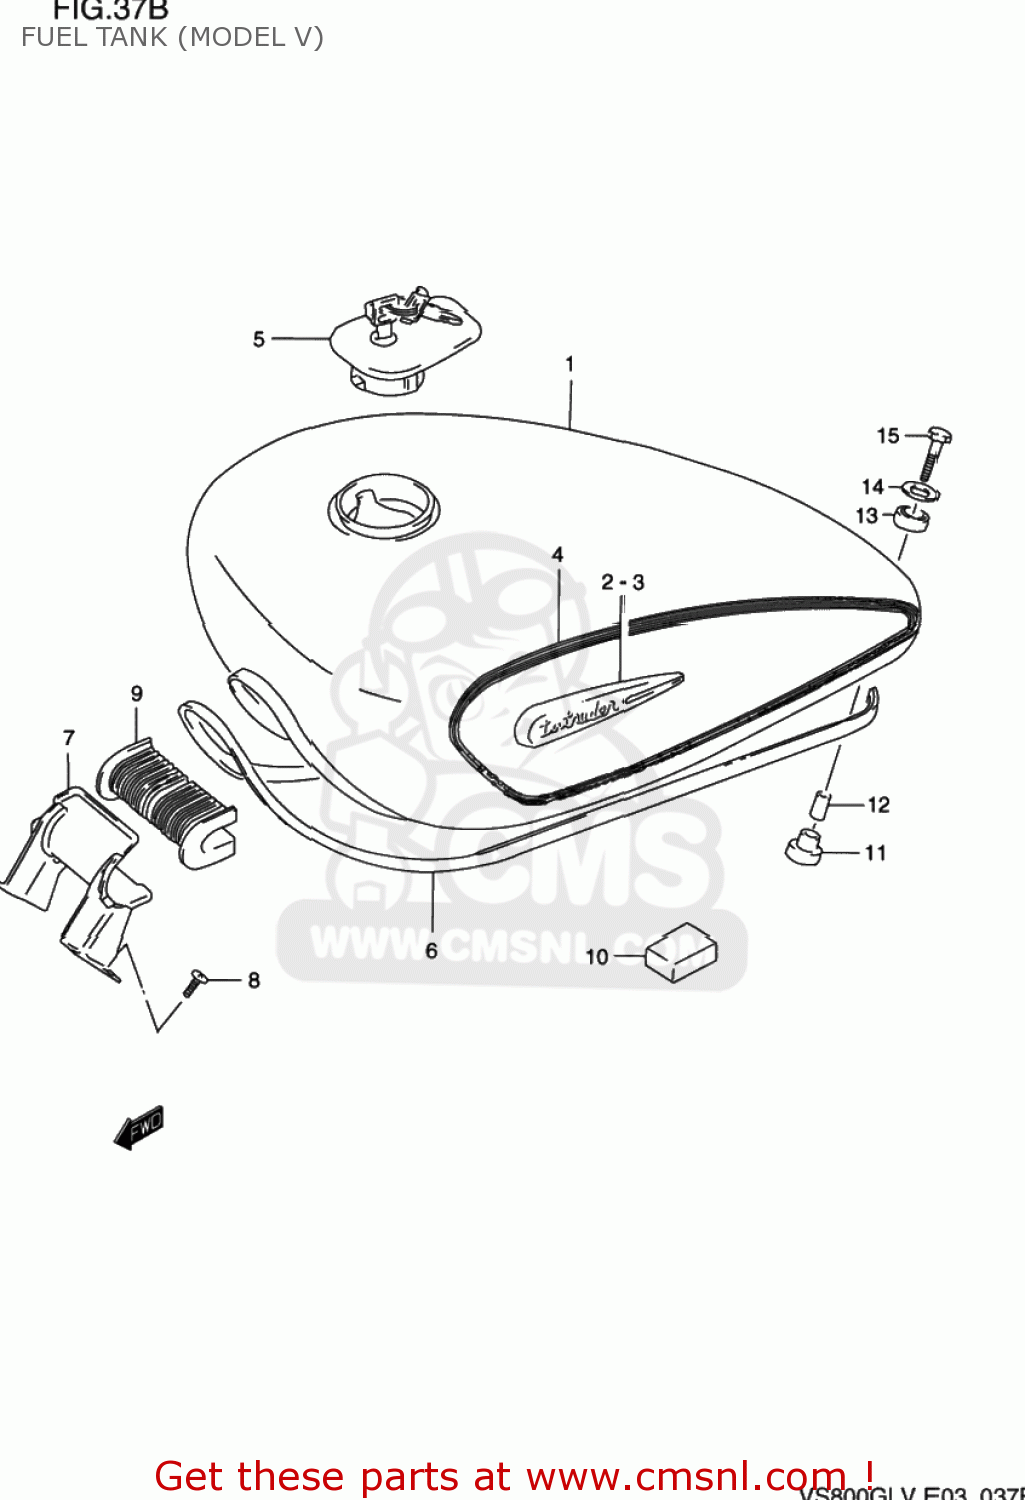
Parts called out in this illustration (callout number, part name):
1	TANK ASSEMBLY,FUEL (RED)
2	EMBLEM,FUEL TANK,R
3	EMBLEM,FUEL TANK,L
4	TAPE SET,FUEL TANK
5	CAP SET,FUEL TANK
6	MOLDING
7	BRACKET,FUEL TANK FR
8	SCREW
9	CUSHION,FUEL TANK FR
10	CUSHION
11	CUSHION
12	SPACER(6.5X9X21.5)
13	CUSHION
14	WASHER (6.5X24X1.6)
15	SCREW
